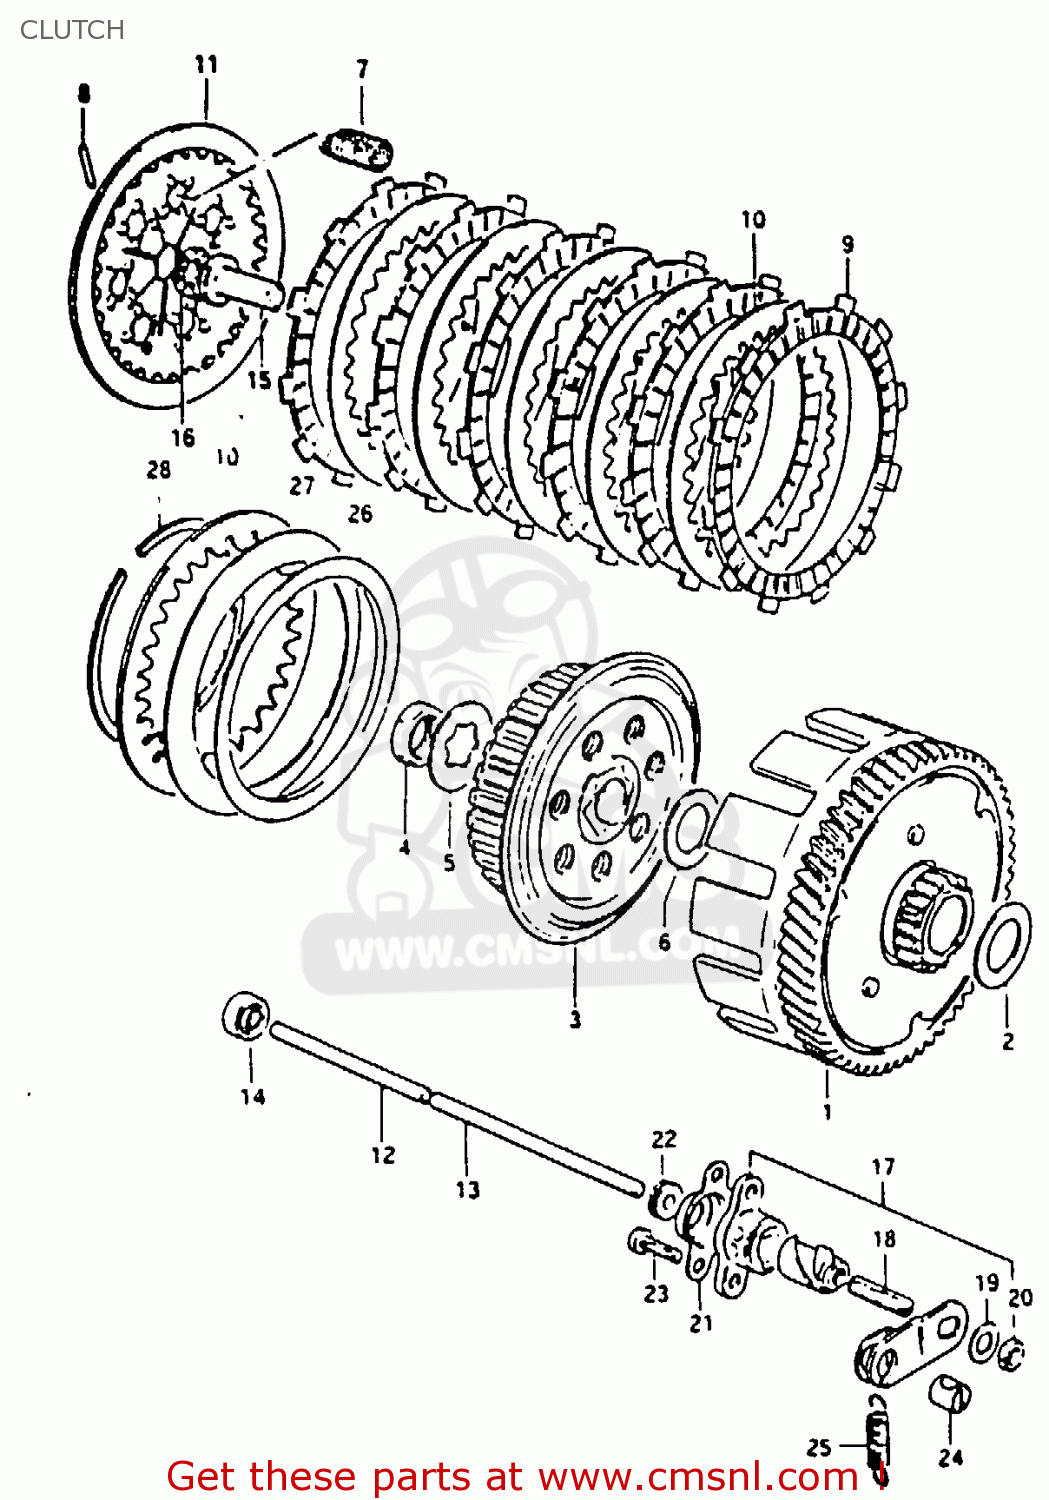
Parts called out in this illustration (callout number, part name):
1	GEAR, PRIMARY DRIVEN
2	WASHER
3	HUB,CLUTCH SLEEVE
4	NUT
5	WASHER,LOCK
6	WASHER
7	SPRING
8	PIN(2.5X19.8)
9	PLATE,CLUTCH DRIVE (NAS)
10	PLATE,CLUTCH DRIVEN (NAS)
11	PLATE,CLUTCH PRESSURE
12	ROD,CLUTCH PUSH
13	ROD,CLUTCH PUSH
14	OIL SEAL
15	PIECE,CLUTCH PUSH
16	BEARING(10X22X2.8)
17	SCREW ASSY,CLUTCH RELEASE
18	SCREW(6X25)
19	WASHER(6.5X16X1.2)
20	NUT 6MM
21	COVER,CLUTCH RELEASE SCREW
22	SEAL,DUST(5.3X13X5)
23	SCREW
24	PIECE,RELEASE ARM END
25	SPRING
26	SEAT,WAVE WASHER
27	WASHER
28	CIRCLIP
